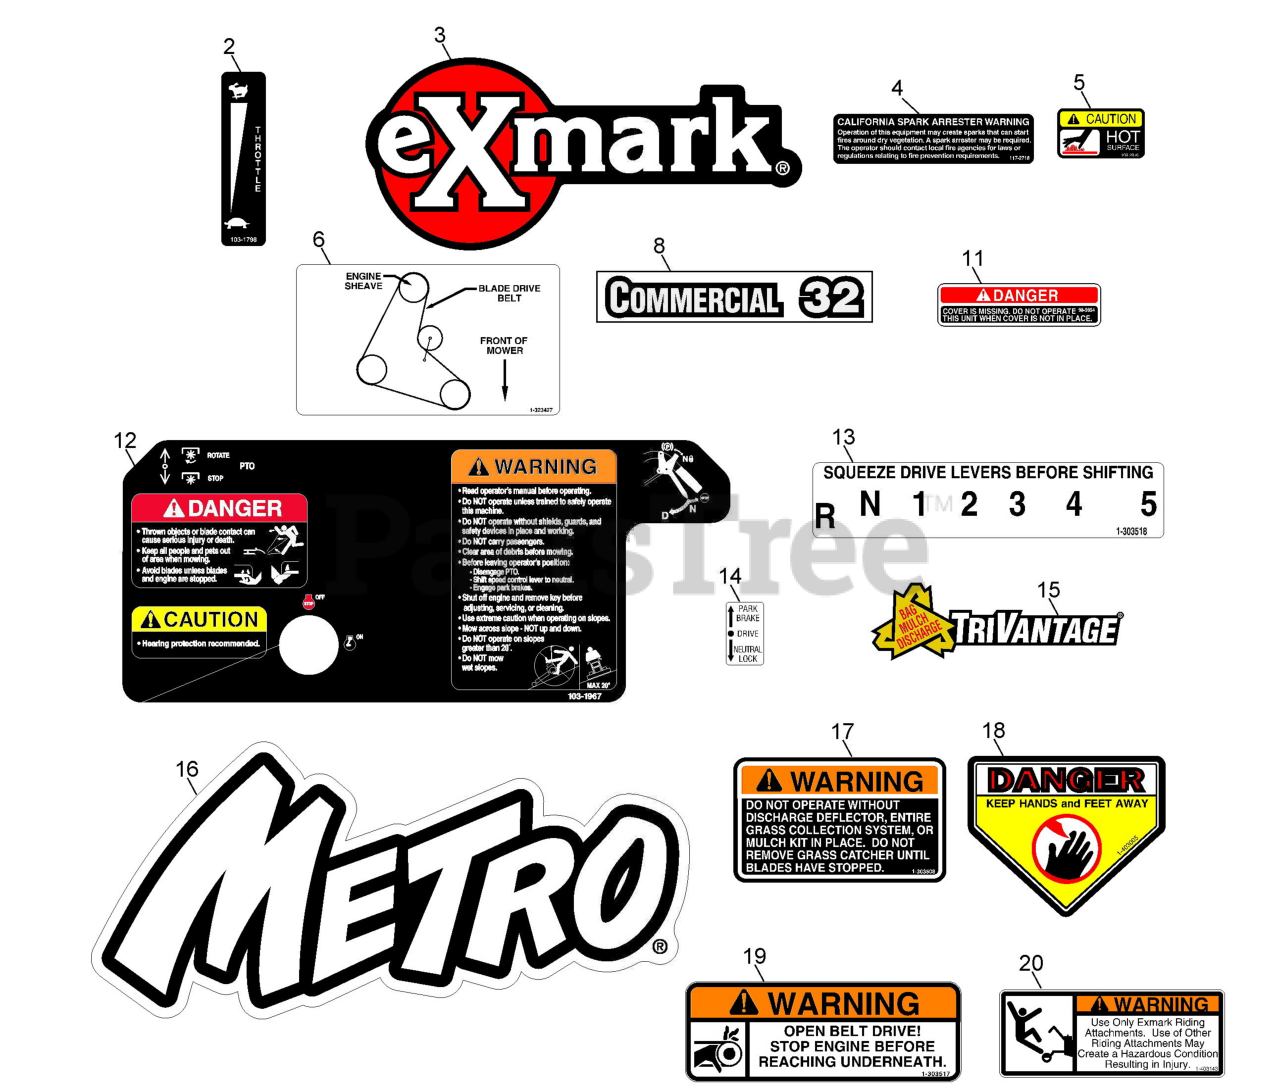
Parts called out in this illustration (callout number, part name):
2	DECAL,THROTTLE ONLY
3	DECAL,EXMARK LOGO
4	DECAL-ARRESTER, SPARK
5	DECAL-CAUTION
6	DECAL,BELT ROUTING 32/36
8	DECAL,COMMERCIAL 32
11	DECAL-COVER, MISSING
12	DECAL,CONSOLE
13	DECAL,SHIFTER
14	DECAL,NEUTRAL/BRAKE
16	DECAL,METRO MODEL
17	DECAL-WARNING, DISCHARGE
18	DECAL-DANGER
19	DECAL,BELT DRIVE
20	DECAL,SULKY WARNING
